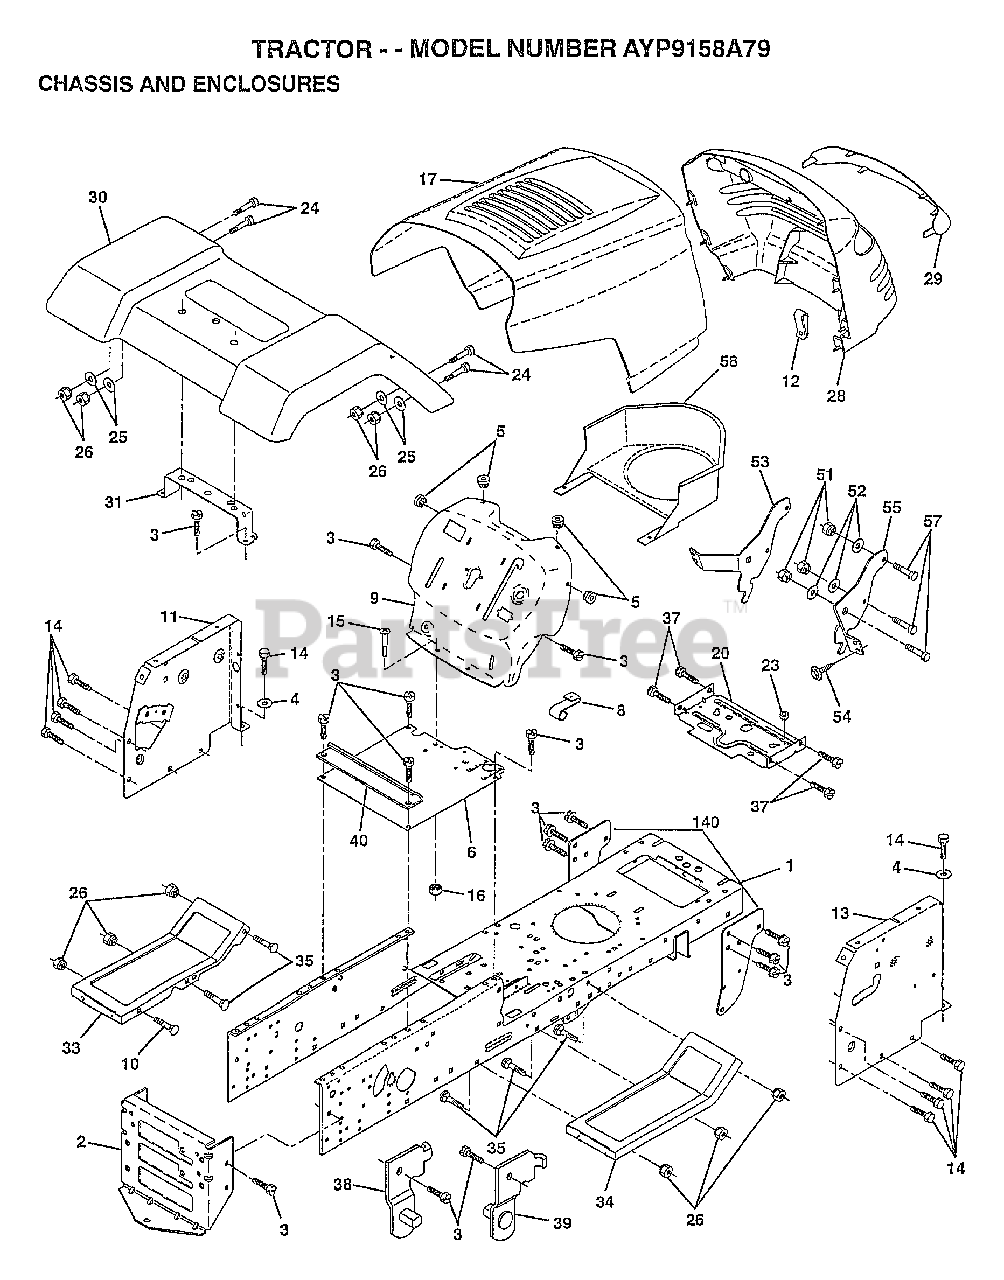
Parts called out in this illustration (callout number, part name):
1	CHASSIS ASM
3	SCREW
4	WASHER
5	BUMPER-HOOD/DASH
6	SADDLE
8	CLIP.RETAINER
9	DASH SILKSCREEN
11	"PANEL-DASH,LH"
12	CLIP.TINNERMAN
13	"PANEL-DASH,RH"
14	SCREW LT
15	SCREW
17	HOOD.STL.PRV.LB
20	"PLATE-MTG,BATT/FU"
24	BOLT
25	WASHER
26	NUT
28	GRILL
29	LENS.EURO.W/DECAL
31	BRACKET SUPT FEND
33	FOOTREST.LT.LT/GT
34	FOOTREST.RH.LT/GT
35	BOLT
37	SCREW LT
38	BRACKET ASM LH
39	BRACKET ASM RH
40	SPACER FENDER LT
51	NUT
53	BRACKET.GRILLE.LH
55	BRACKET.GRILLE.RH
58	AIR DUCT
140	BRKT SUSPENSION
